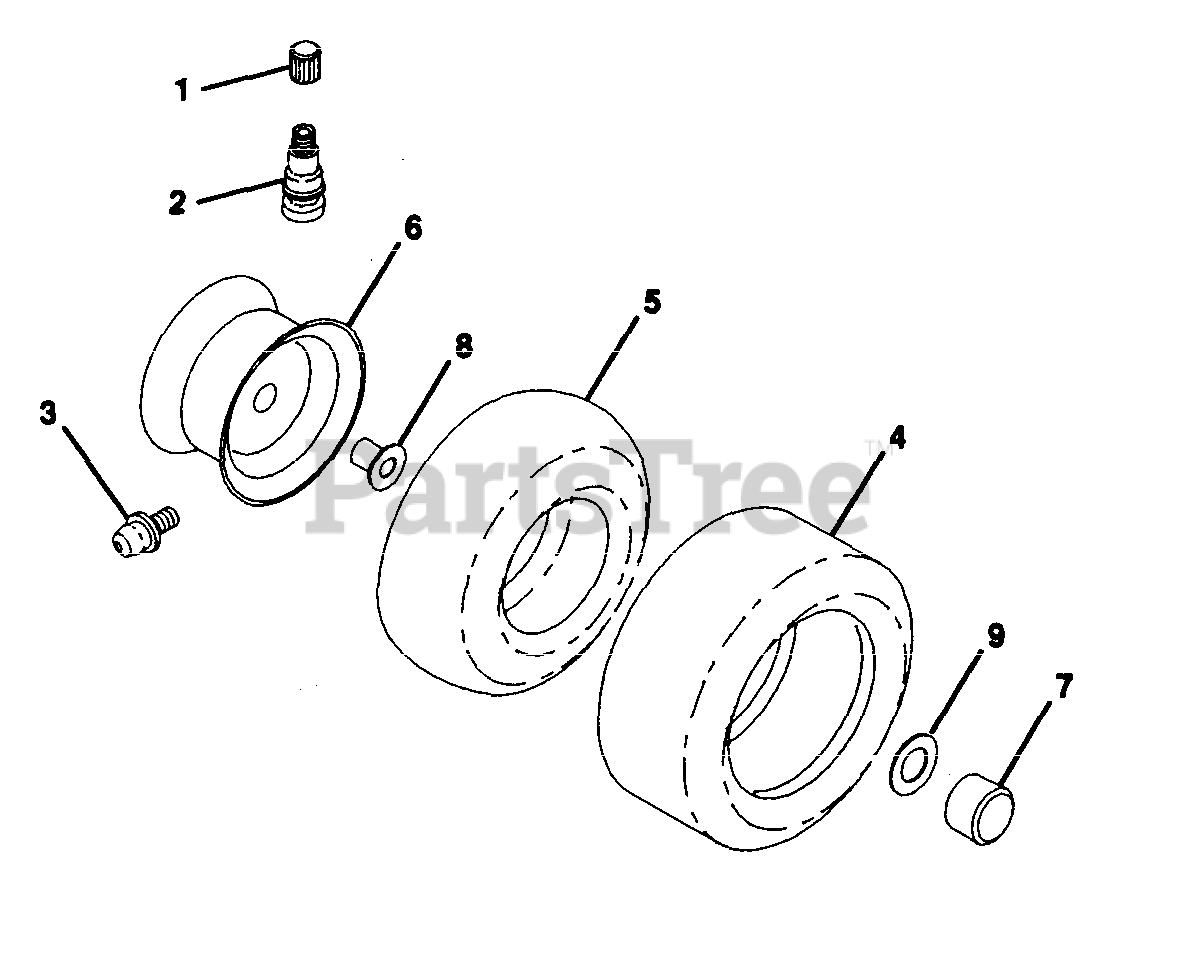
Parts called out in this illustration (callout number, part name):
1	Cap, Valve, Tire
2	Stem, Valve
3	Fitting, Grease
4	Tire, Front
4	Tire, Rear
5	Tube, Front Tire
5	Tube, Rear Tire
6	Rim Assembly, Front
6	Rim Assembly, Rear
8	Bearing, Flange
9	Washer 25/32 x 1-5/8 x 16 Gauge
